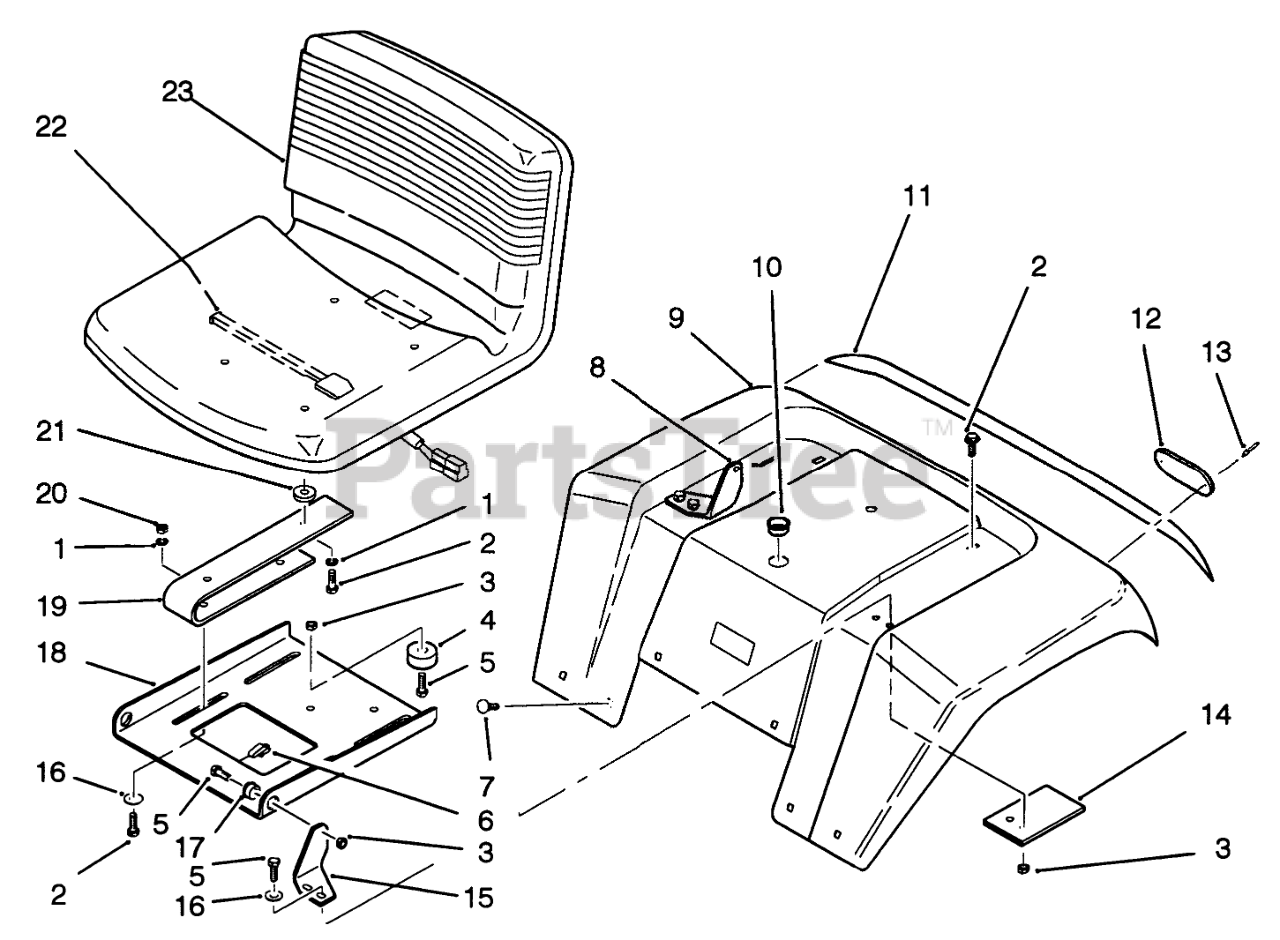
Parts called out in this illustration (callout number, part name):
1	WASHER-LOCK
2	SCREW-HH
3	Nut
4	BUMPER SJ5514 BLACK
5	SCREW-HH
6	J-CLIP
7	NUT-HEX, JAM
8	Bracket-Pivot RH
9	FENDER R
10	BUSHING-NYLON 1.093
11	DECAL-FENDER
12	Reflector
13	Poprivet
14	PLATE R
15	BRACKET-PIVOT L.H B
16	WASHER-PLAIN
17	BUSHING
18	PLATE-SEAT PIVOT B
19	SPRING-SEAT B
20	NUT-HEX
21	SPACER-NYLON
22	SWITCH-SEAT
23	SEAT V-410
